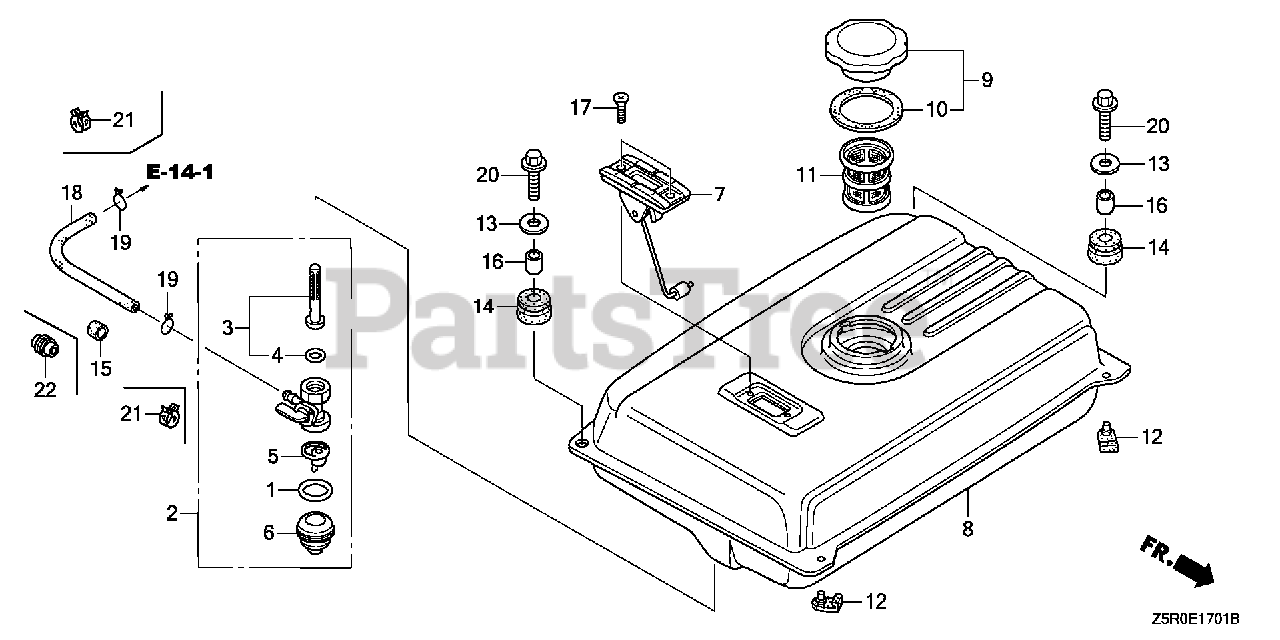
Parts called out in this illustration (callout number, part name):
15	RUBBER, FUEL (9X15X10)
18	TUBE, FUEL (4.5X165) (FKM)
21	CLAMP, TUBE (D8)
22	RUBBER, FUEL (9X15X20)
